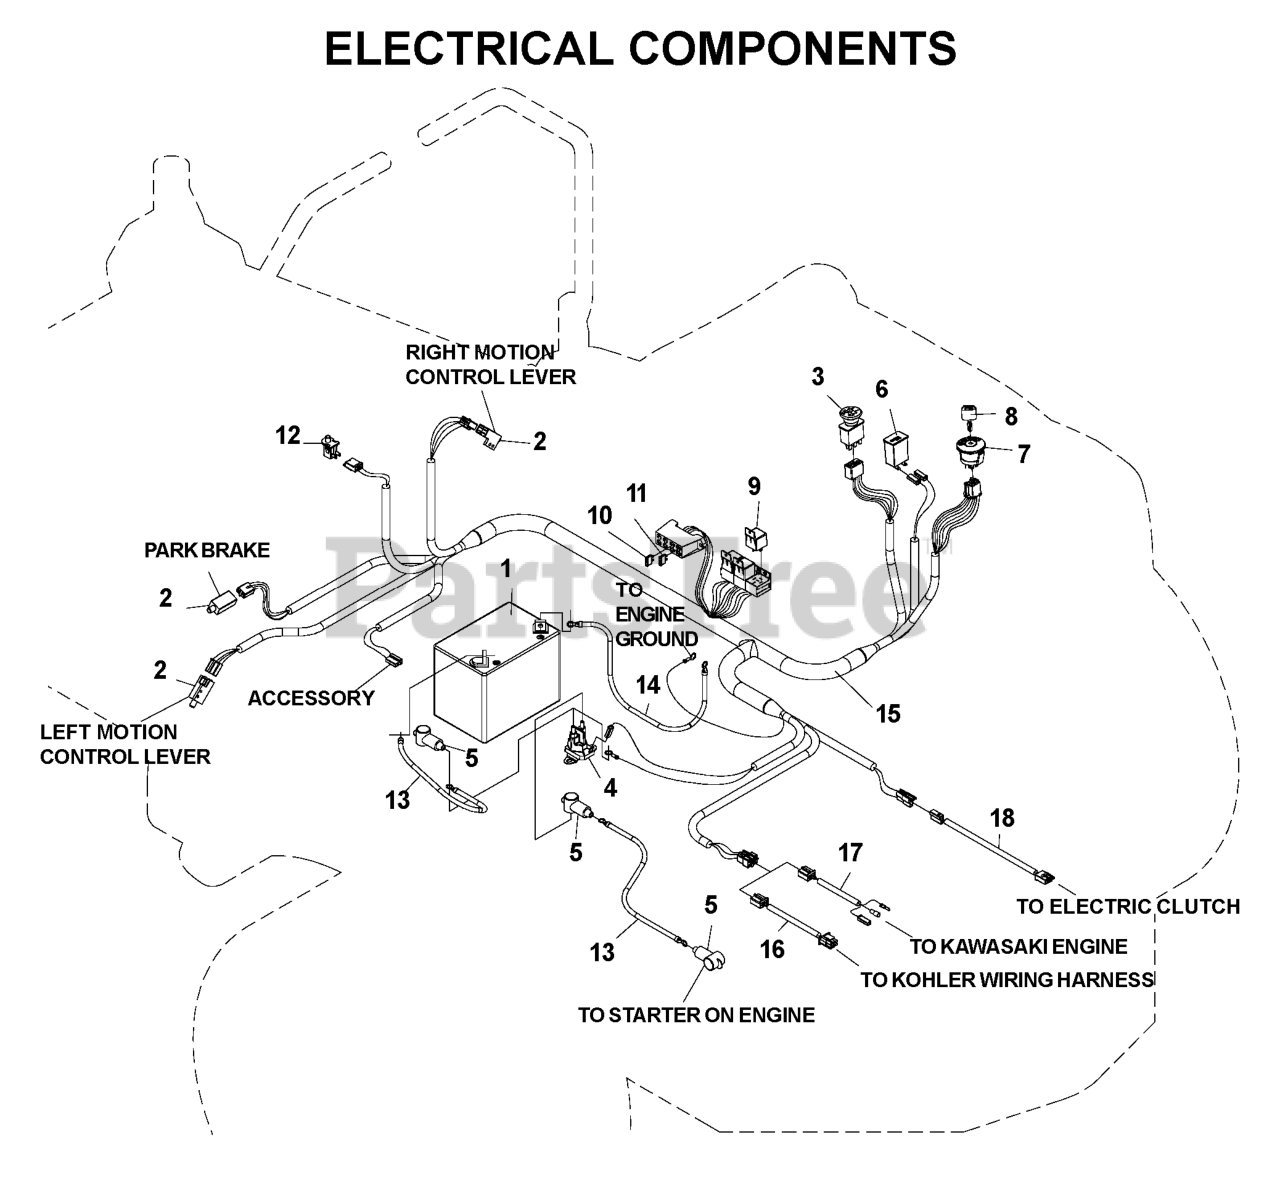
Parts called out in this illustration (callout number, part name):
1	BATTERY, 12 V 330 AMP
2	SWITCH, INTERLOCK
3	RP.SWITCH, BLADE
6	HOUR METER
7	RP IGNITION SWITCH
8	KEY
10	FUSE, 20 AMP 32 VOLT ATO
11	FUSE, 7.5 AMP 32 VOLT ATO
12	SEAT SWITCH
13	BATTERY CABLE-POS
14	BATTERY CABLE-NEG
15	WIRING HARNESS
16	KOHLER PIGTAIL-CV490S
17	KAW PIGTAIL
18	CLUTCH HARNESS
